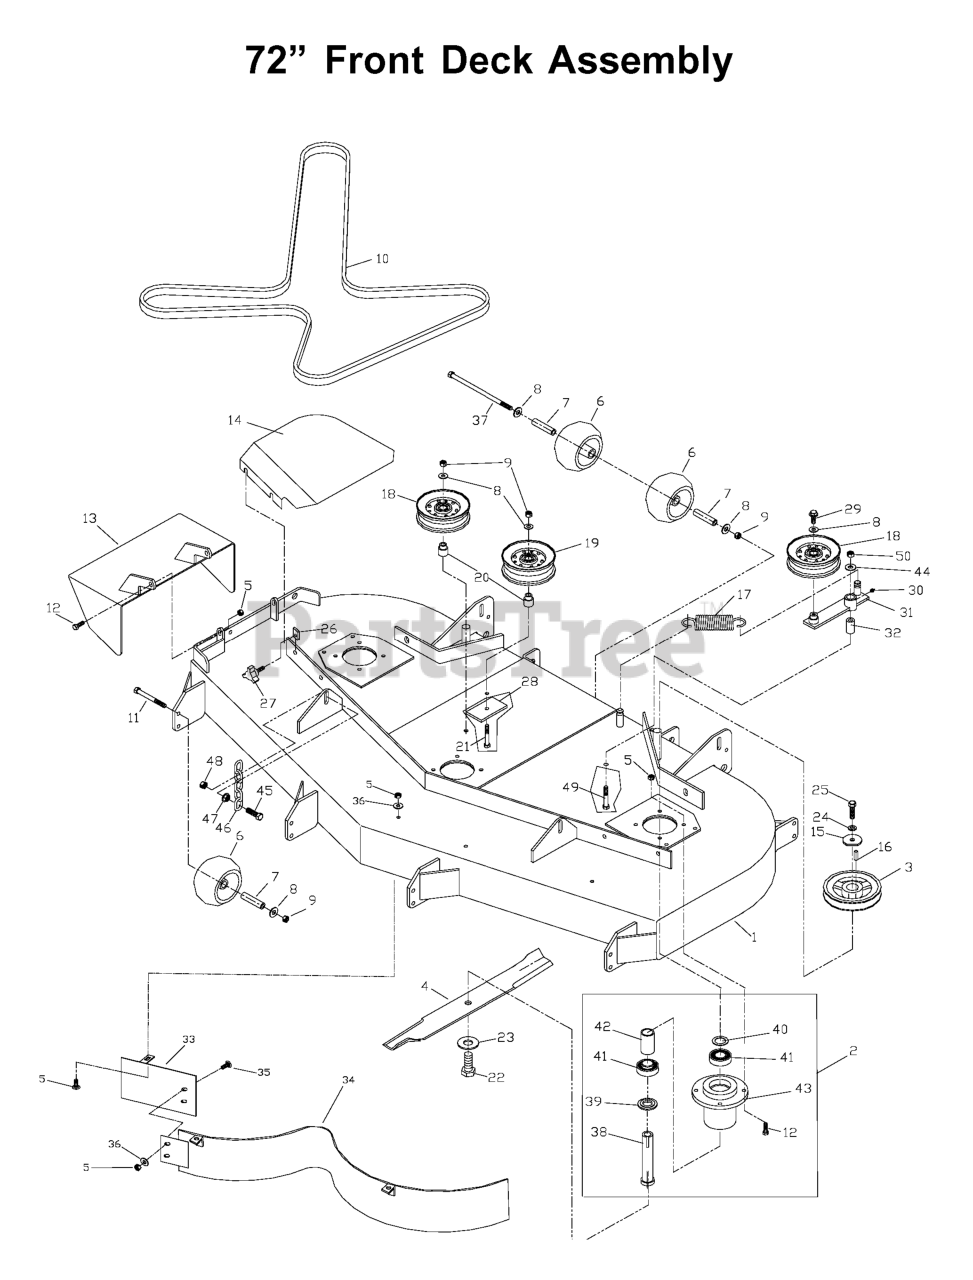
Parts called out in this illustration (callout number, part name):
1	DECK W/DECALS 72" HUS WSL
2	SPINDLE ASSY-72"
4	BLADE OEM - 25"
5	NUT 5/16C CENTERLOCK
6	ANTI-SCALP ROLLER
8	WASHER 3/8 FLAT
9	NUT 3/8C CENTERBLOCK
10	BELT, DECK 72"
11	HCS 3/8C X 3 1/2
12	HCS 5/16C X 1 1/4
13	DISCHARGE CHUTE
14	BELT SHIELD RH ORANGE
15	SPINDLE WASHER
16	KEY 1/4 SQ X 1 1/8
17	DECK SPRING
18	IDLER PULLEY
19	IDLER PULLEY (TALL)
20	IDLER BUSHING
21	HCS 3/8C X 3
22	HEX SCREW-5/8F X 2 GR8
23	BELLEVILLE SPRING WASHER
24	WASHER 7/16 LOCK
25	HCS 7/16F X 1 1/2
26	U-CLIP 5/16-18 NUT RETAINER
27	KNOB W/STUD
28	SUPPORT PLATE
29	4CS 3/8C X 1 SERRATED HEAD
30	ZERK
32	PIVOT BUSHING
33	BAFFLE/CENTER-FLAT BLK
34	BAFFLE/CENTER-CURVED
35	CARRIAGE BOLT 5/16C X 5/8"
36	WASHER 5/16 FLAT
37	BOLT 3/8 X 6" GRD 8
38	SPINDLE SHAFT
39	MACHINERY BUSHING 10 GA.
40	BUSHING.MACHINE.18.GAUGE
41	BEARING
43	HOUSING, DIE CAST
44	WASHER 1/2 FLAT
45	HCS 7/16C X 1 1/2
46	LIFT CHAIN
47	NUT 7/16C WHIZ
48	NUT 7/16C CENTERLOCK
49	HCS 1/2C X 3 1/4
50	NUT 1/2-13 HEX NYLOC ZD
539105566	BELT SHIELD LH ORANGE
